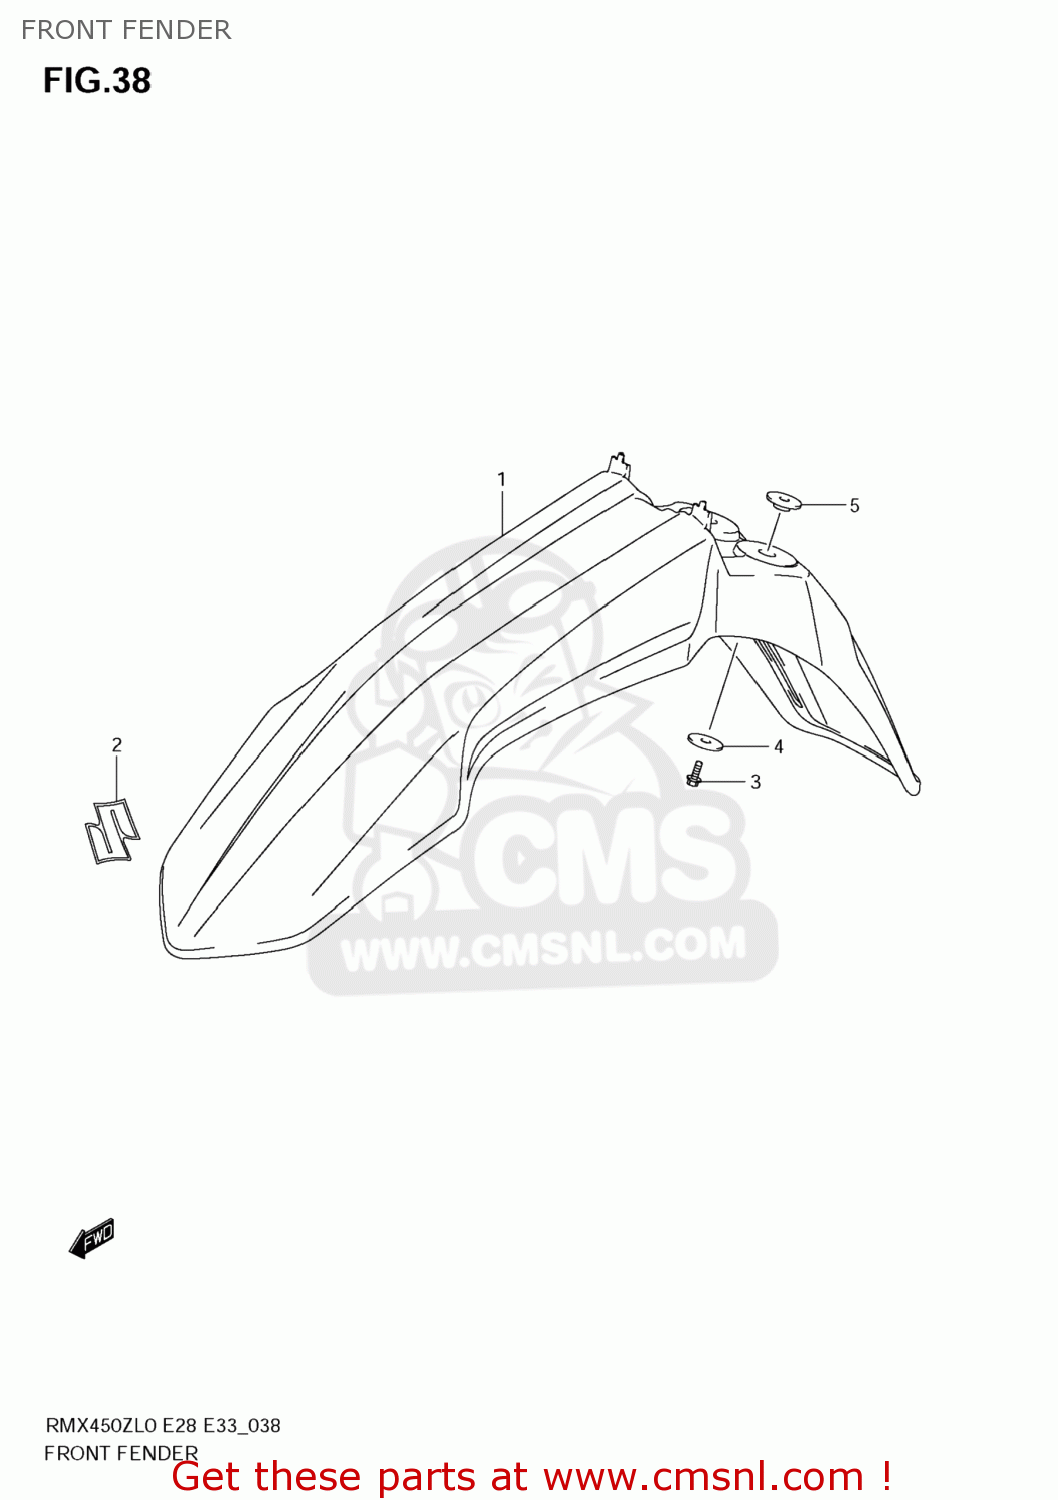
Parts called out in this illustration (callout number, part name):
1	FENDER,FR
2	EMBLEM,S
3	BOLT
4	WASHER,FUEL TANK FR
5	WASHER
